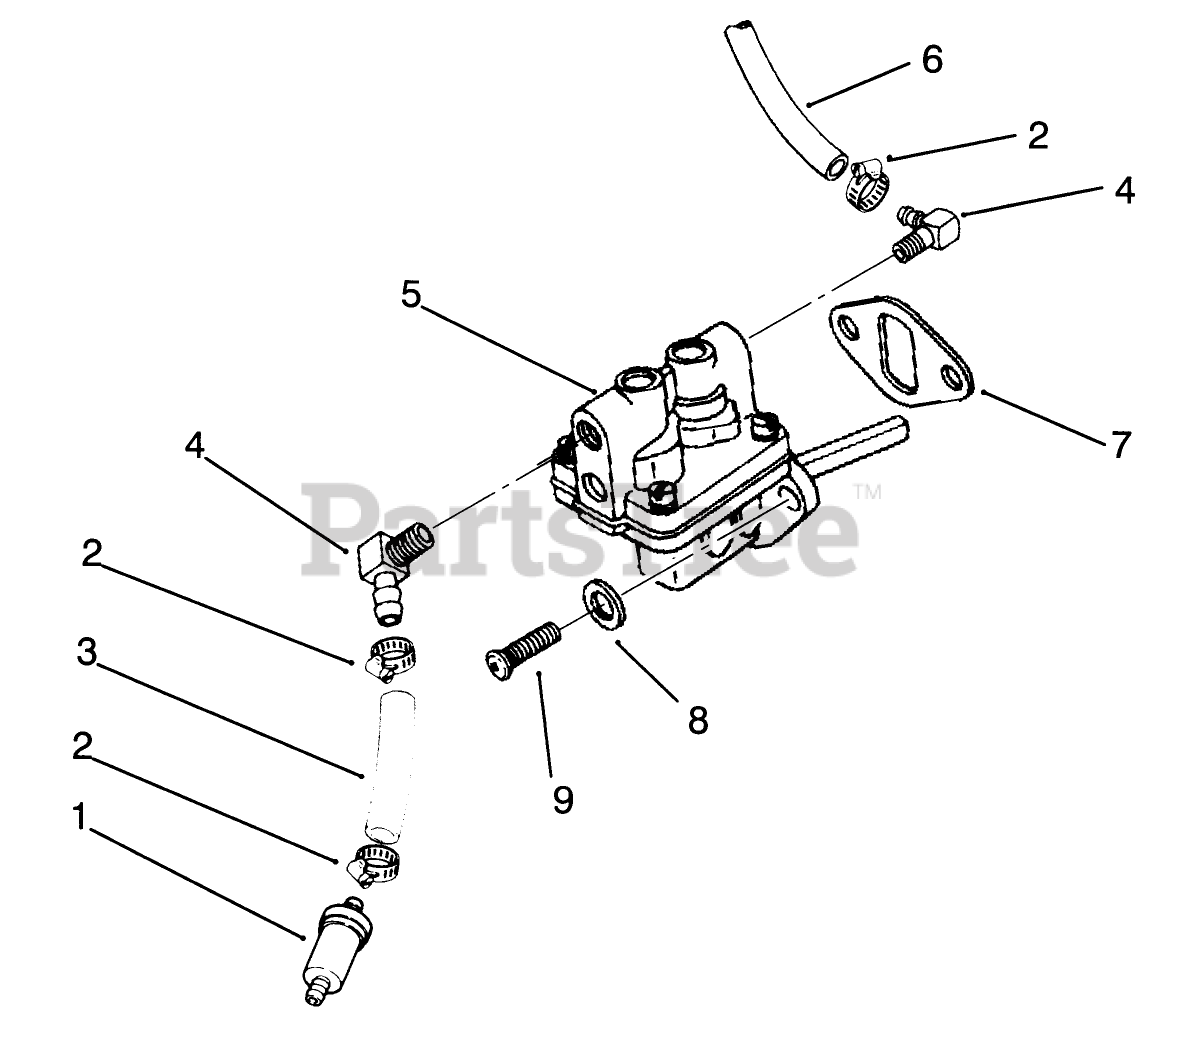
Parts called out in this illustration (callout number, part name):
1	Filter-Fuel
2	Clamp
3	Line-Fuel
4	Connector-90deg.
5	Fuel Pump Assembly (Incl. Ref. #7 & 8)
7	Gasket-Fuel Pump
8	Washer
9	Screw-T.H.
